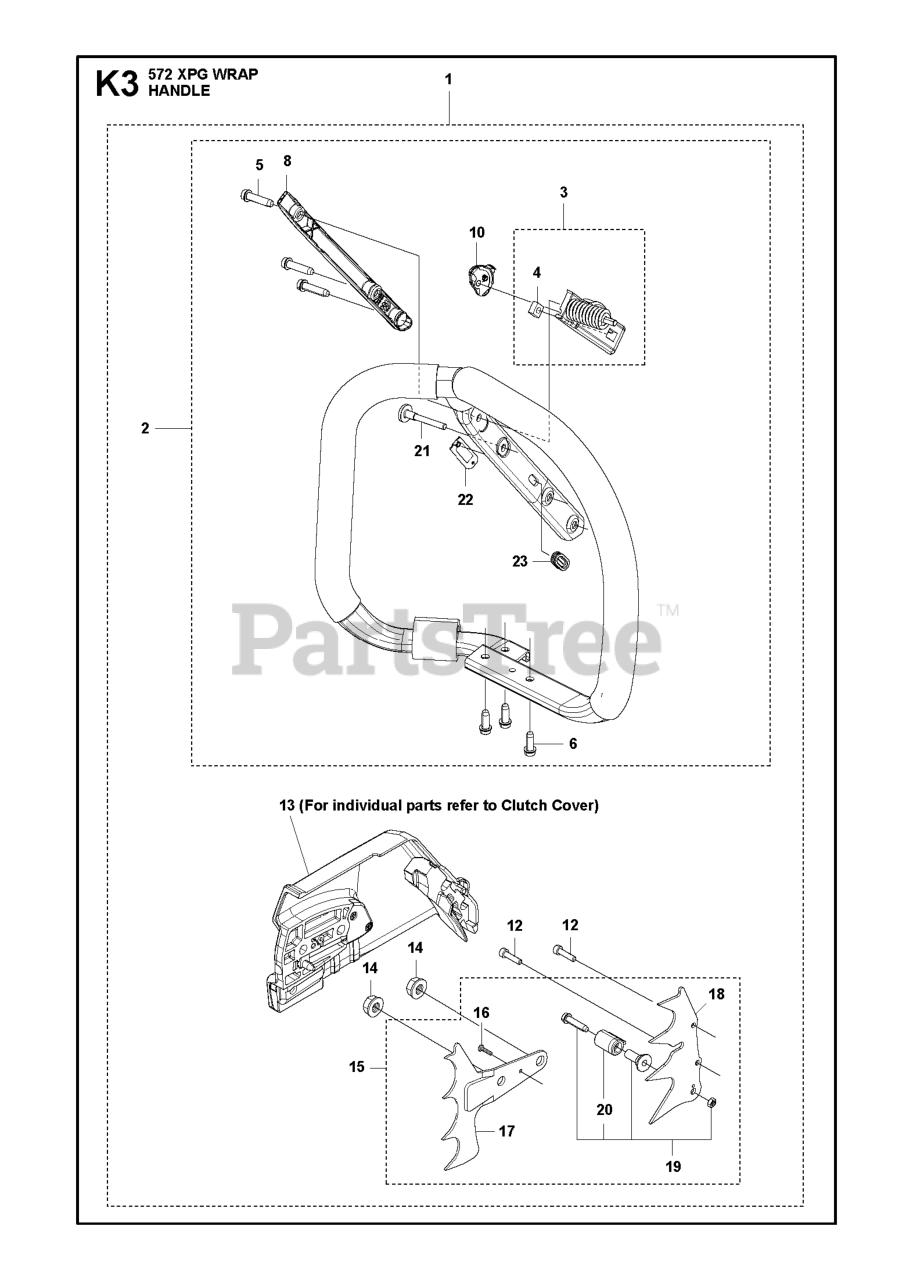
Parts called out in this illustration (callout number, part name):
1	FRONT HANDLE ASSY KIT 572XPG W
2	FRONT HANDLE ASSY KIT WRAP HEA
3	ANTIVIBRATION ELEMENT ASSY HEA
3	ANTIVIBRATION ELEMENT ASSY HAR
8	COVER FRONT HANDLE HEAT
12	SCREW ITXSCM
13	CLUTCH COVER ASSY
14	NUT M8 FLANGE
15	SPIKE KIT WESTCOAST H565/H572
16	SCREW CITXPANT
17	FELLING DOG
18	FELLING DOG
19	CHAIN CATCHER H565/H572 KIT
21	SCREW ITXPANM MOVEMENT LIMITER
22	PROTECTION FRONT HANDLE, HEAT
